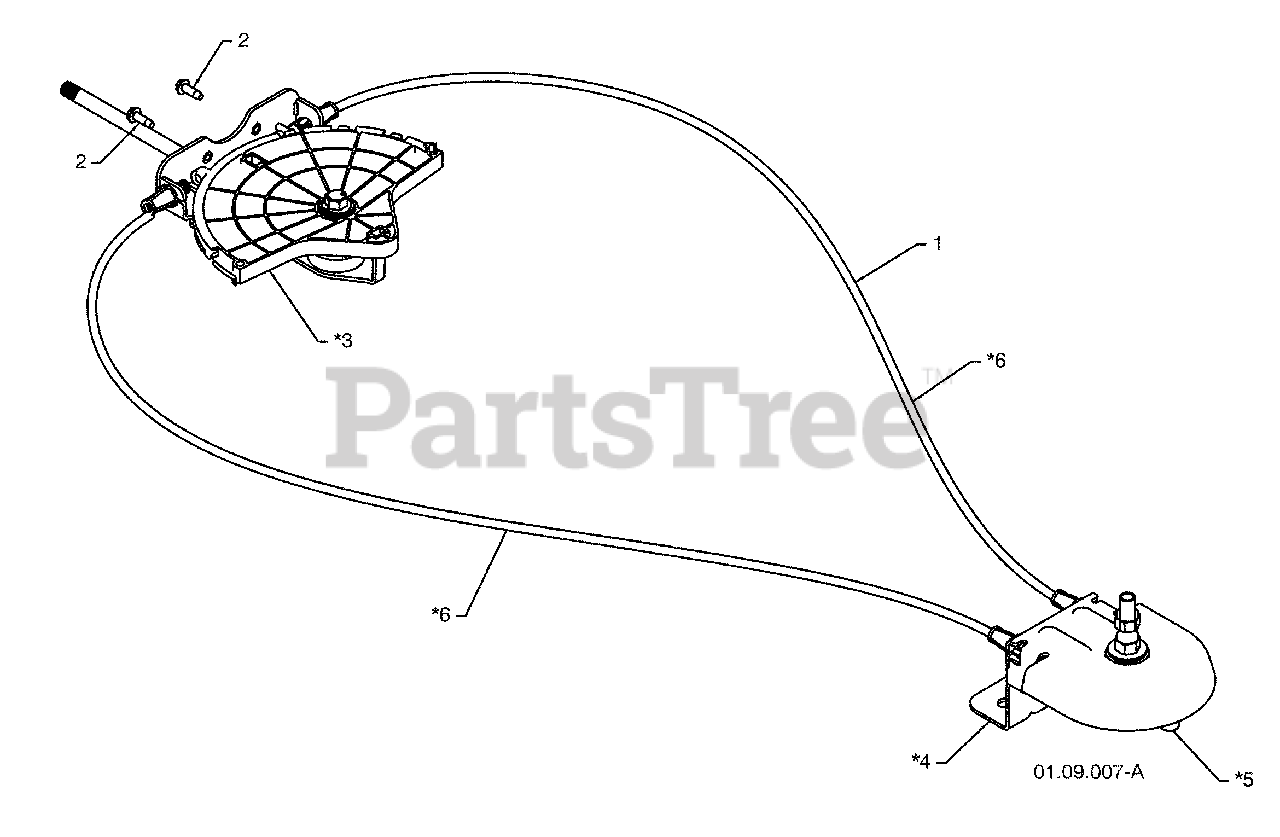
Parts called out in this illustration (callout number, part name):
1	LEVER/CABLE ROTATOR ASSEMBLY
2	SCREW 10--24 X .625
3	ROTATOR HEAD
4	ROTATOR PIVOT BRACKET
5	PULLEY PIVOT
6	CABLE ASSEMBLY
